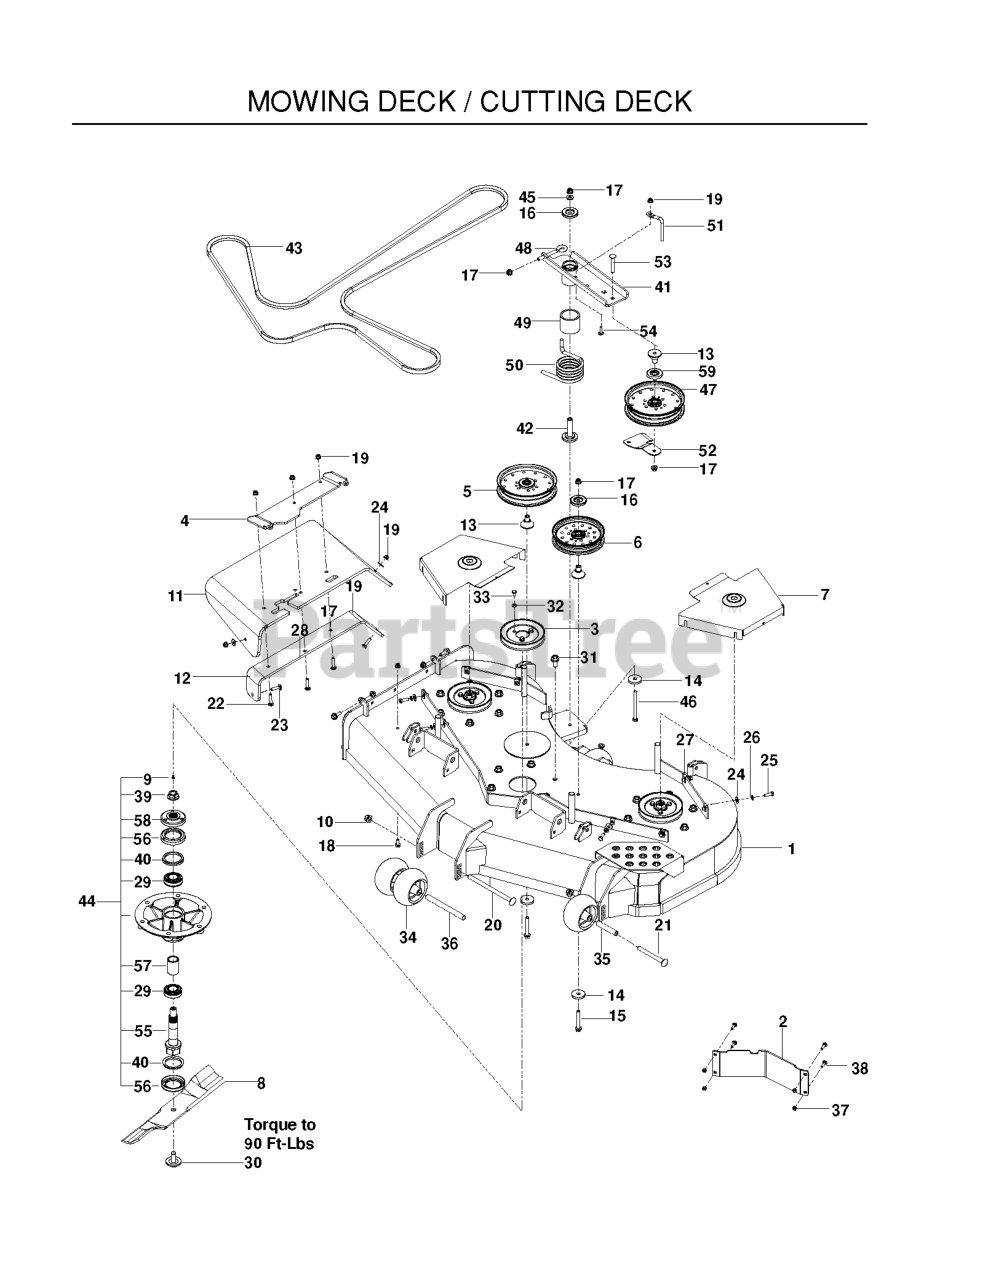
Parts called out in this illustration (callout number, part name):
1	DECK.FAB.54".W/DECALS.ORANGE
2	BAFFLE, DIVERTER 54"/60" LH
3	PULLEY - 5.93 OVER PINS
4	BRKT - CHUTE MTG BLACK
5	PULLEY - 7" NARROW
6	PULLEY IDLER, 6" NARROW
7	SHIELD,BELT, 60" ORANGE
8	BLADE, 19"
9	ZERK
10	NUT, 1/2-13 HEX FLG NYLOC ZD
11	CHUTE, DISCHARGE 48-52
12	BRKT, CHUTE SUPPORT BLACK
13	BEARING, IDLER ARM
14	SPINDLE WASHER
15	HHFS 3/8-16 X 2 3/4
16	DUST SHIELD
17	NUT 3/8-16 HEX FLG NYLOC ZD
18	HHFS 5/16-18 X 3/4
19	5/16-18 NYLOC FLANGE NUT
20	RHSNB 1/2-13 X 8 GR5 ZD
21	RHSNB 1/2-13 X 4.75 GR5 ZD
22	RHSNB 5/16-18 X 1-1/2 GR 5 ZD
23	BOLT, CARRIAGE 5/16X1-1/4
24	WASHER 5/16 FLAT
25	HCS 5/16C X 1
26	WASHER.LOCK.HVY.HLCL.SPR.5/16
27	U-CLIP 5/16-18 NUT RETAINER
28	HHFS 3/8-16 X 1 GRD 5 ZD
29	BEARING - 206KRR8
30	BLADE BOLT/WASHER
31	HHFS 1/2-13 X 1 GR5 ZD
32	WASH 5/16 DISC SPRING ZD
33	HCS 5/16-18 X 1/2 GR 5 ZD
34	ROLLER, GAUGE .635 BORN
35	TUBE, ROLLER AXLE
36	TUBE, ROLLER AXLE LONG
37	NUT.1/4-20.HEX.NYLOC.ZD
38	1/4-20X3/4 CARR BLT
39	NUT FLANGE 3/4-16
40	V-RING, 55MM
41	ASSY, IDLER ARM, PZ
42	BEARING, IDLER PIVOT
43	BELT, "B", 169.75
44	SPINDLE ASM. 10"
45	WASHER, 3/8 THICK
46	HCS 3/8-16 X 4-1/2 GR 8 ZD
47	PULLEY - IDLER 7"
48	EYE BOLT, 3/8 X 4"
49	SPACER, IDLER PIVOT
50	SPRING, TORSION, IDLER
51	BELT KEEPER
52	BELT.GUIDE.BLACK
53	CARRIAGE BOLT 3/8-16 X
54	RHSSNB 5/16C X 1.0
55	SHAFT - SPINDLE
56	CUP - DEBRIS
57	SPACER - BEARING
58	HUB - PULLEY
59	SHIELD, DUST
